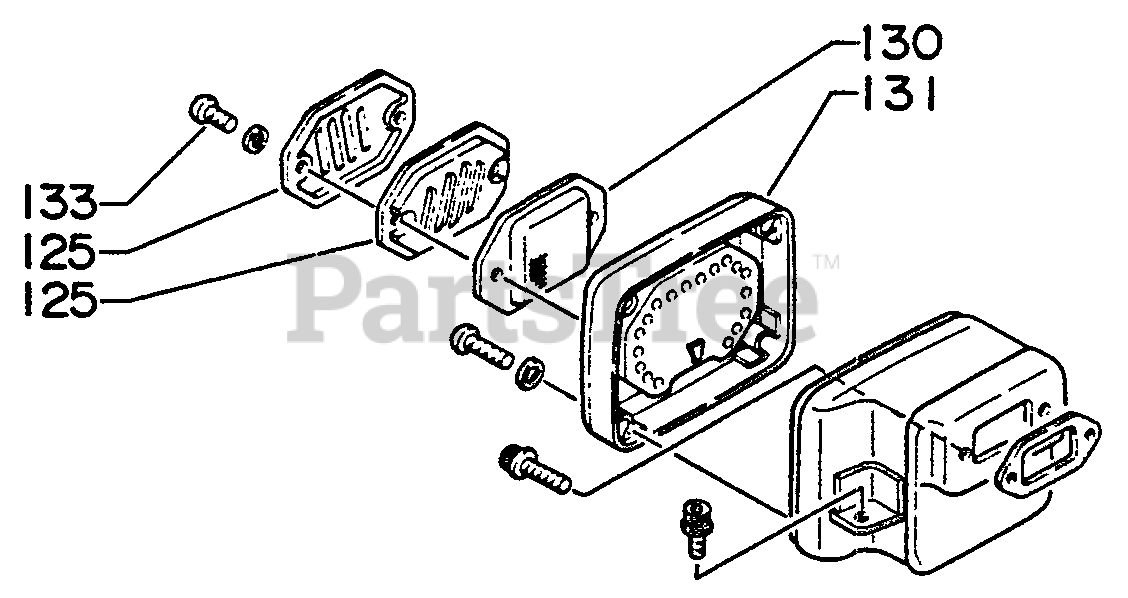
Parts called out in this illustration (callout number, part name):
125	LID, MUFFLER
130	SCREEN, SPARK ARRESTER
131	MUFFLER
133	SCREW
